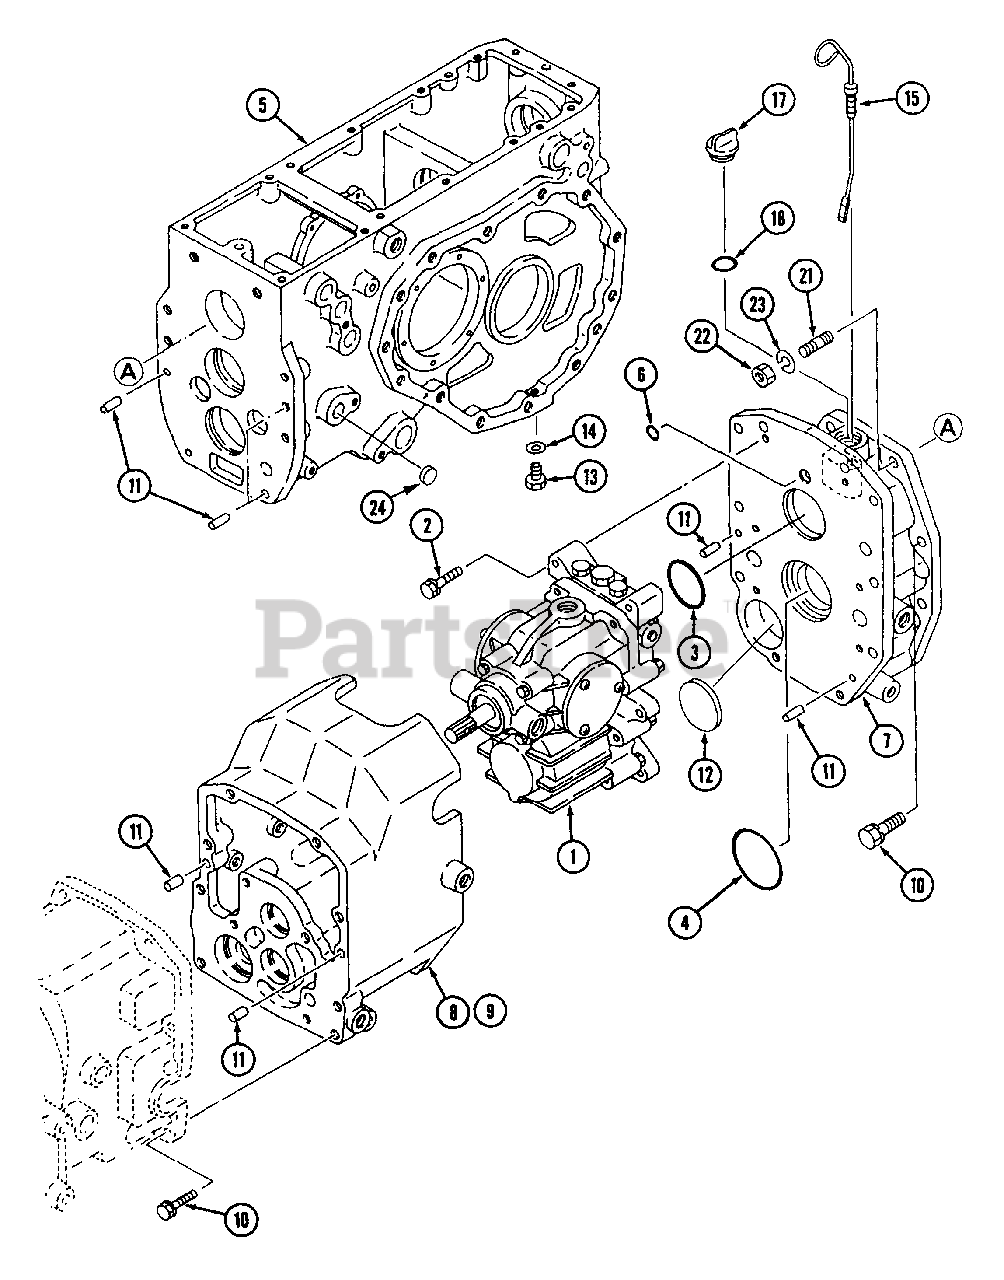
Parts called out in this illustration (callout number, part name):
1	Hydrostatic Unit
5	Case, T/M (STD)
8	Cover, HST
14	Seal, Washer
